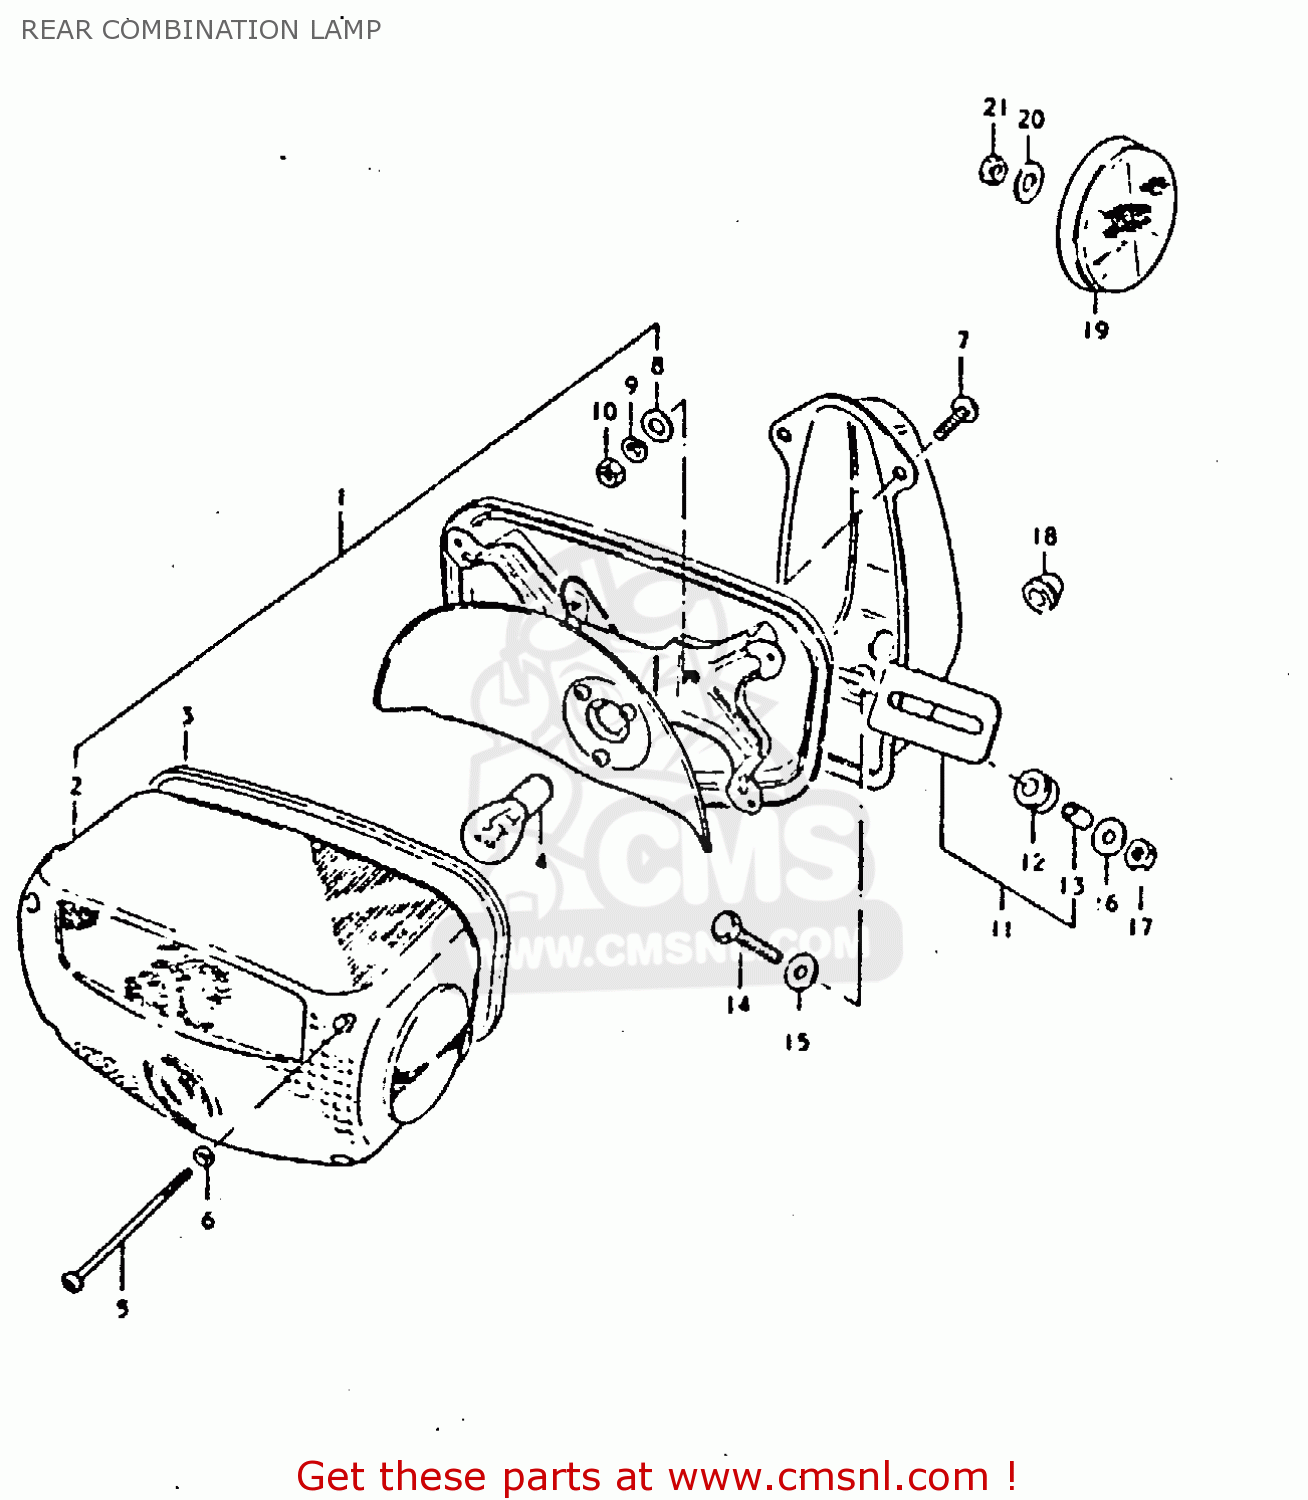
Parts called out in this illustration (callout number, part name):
1	LAMP UNIT, TAIL
2	LENS,REAR COMBINATION LAMP
3	GASKET
4	BULB 12V21/5W
5	SCREW (4X55)
6	GASKET (NAS)
7	SCREW 6X12
8	WASHER
9	LOCK WASHER
10	NUT
11	BRACKET ASSY
12	CUSHION
13	SPACER
14	BOLT
15	WASHER (6.5X20X1.2)
16	WASHER
17	NUT
18	GROMMET
19	REFLEX REFLECTOR,FR
20	WASHER
21	LOCK WASHER
